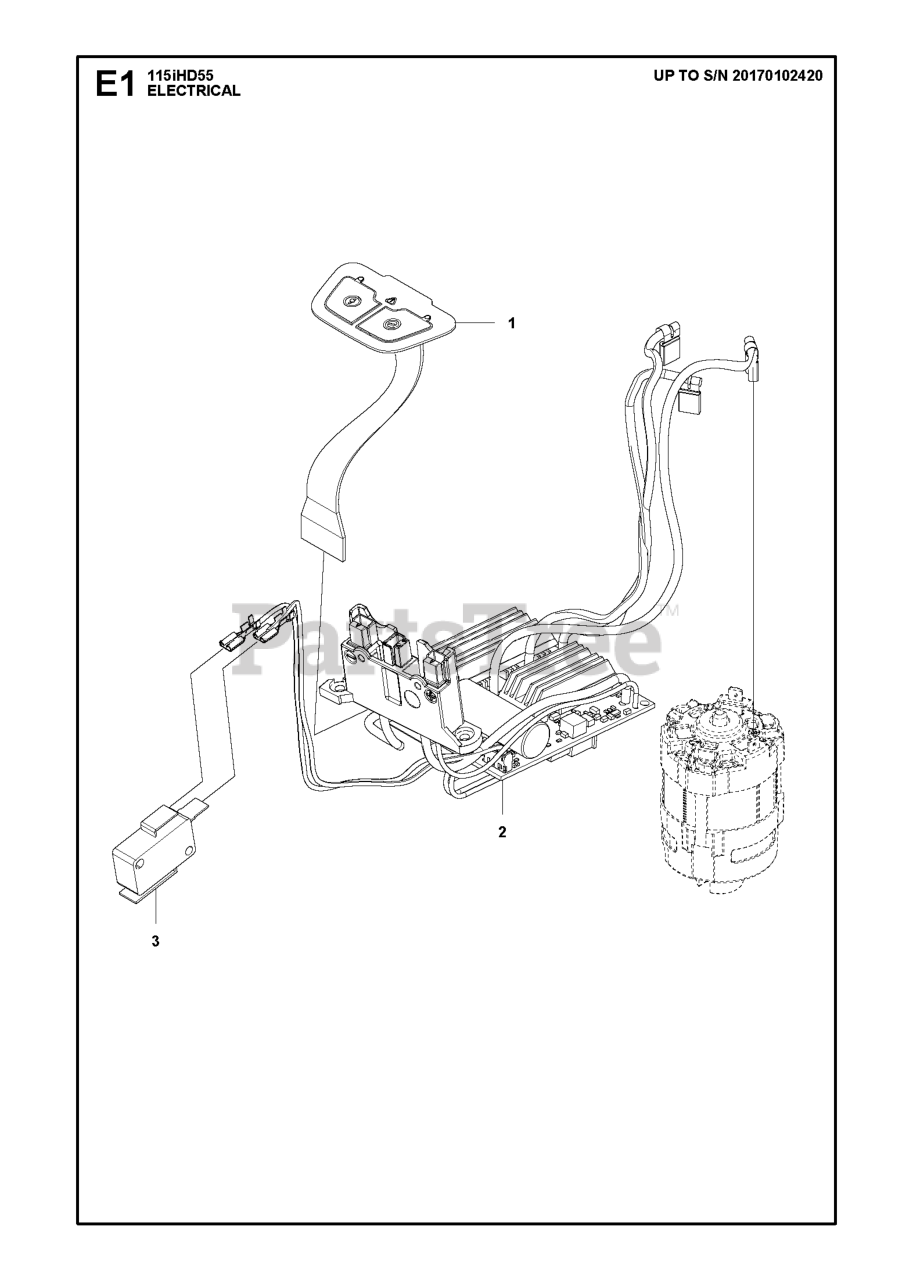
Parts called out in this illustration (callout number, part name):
1	KEYPAD HEDGE TRIMMER
2	CONTROL UNIT CONTROL UNIT BLDC
3	MICRO SWITCH
